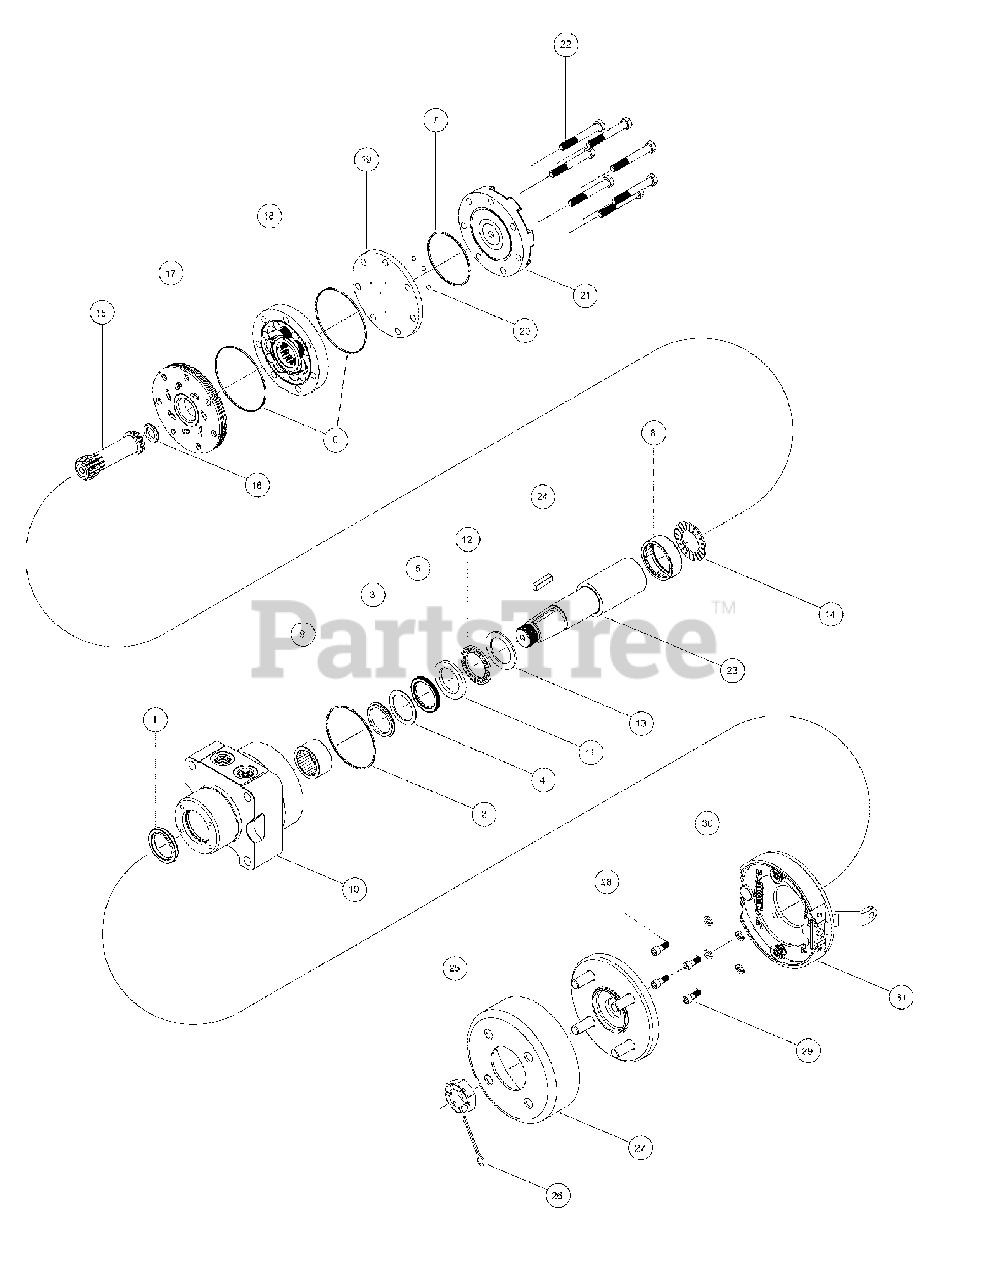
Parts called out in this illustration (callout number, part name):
1	Dust Seal
2	Housing Seal
3	Back Up Ring
4	Back Up Seal
5	Shaft Seal
6	Body Seals
7	Endcover Seal
8	Rear Housing Bearing (Incl 1-8)
9	Front Housing Bearing
11	Front Thrust Washer
12	Front Thrust Bearing
13	Thrust Washer
14	Rear Thrust Bearing
16	Drive Link Spacer
19	Balance Plate
22	Assembly Bolts
27	6" Stamped Drum
28	4-Lug Knott Hub
29	Mounting Bolts
30	Lock Washers
